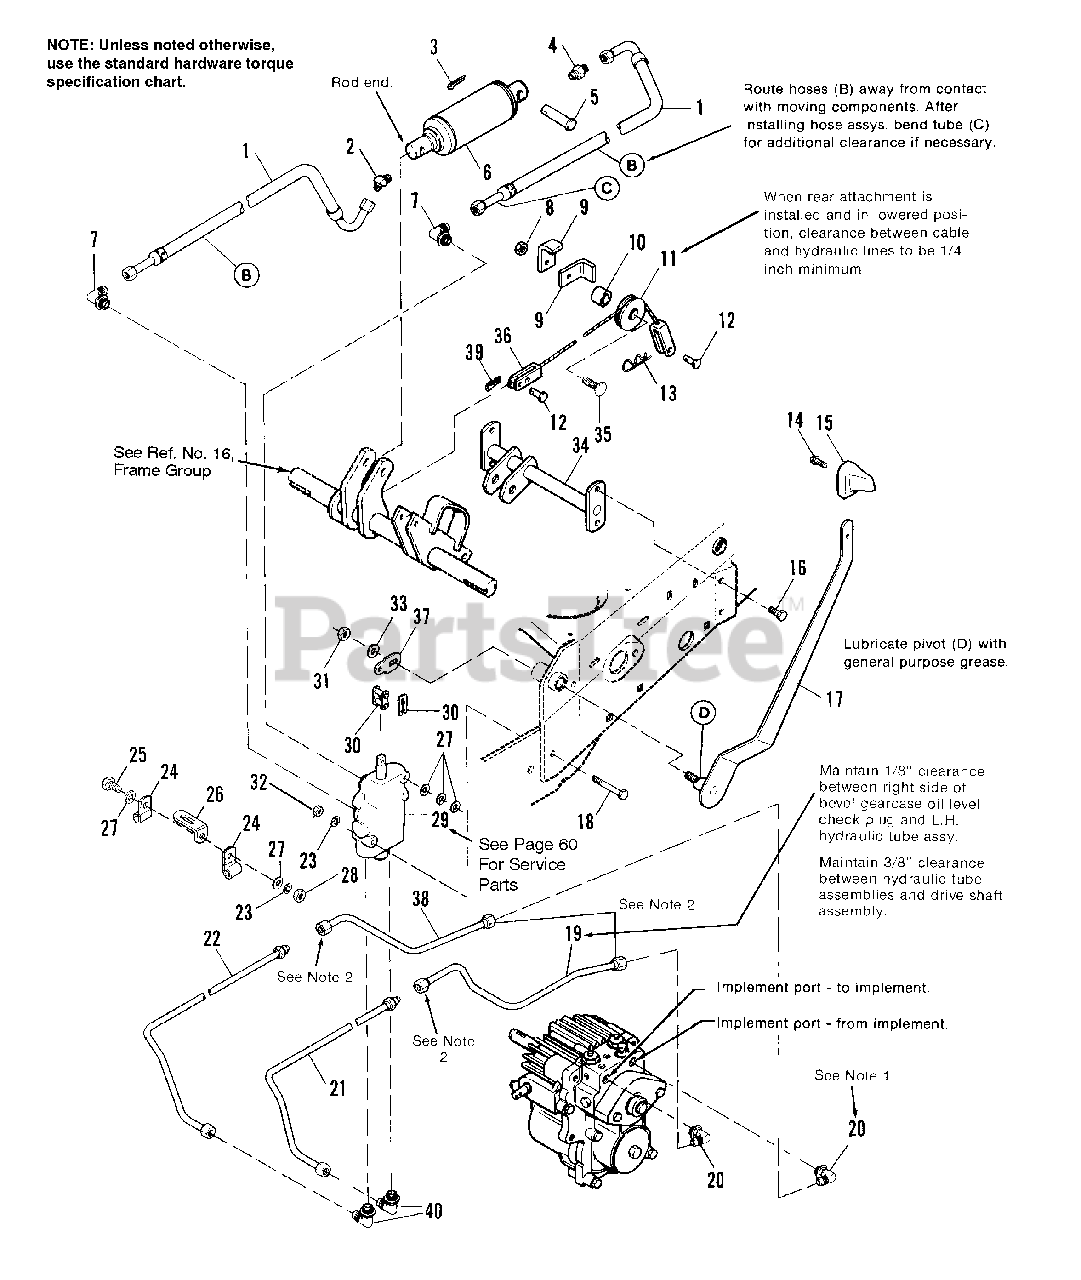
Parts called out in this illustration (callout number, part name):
1	HOSE, Hydraulic
2	FITTING, Elbow, 45°.
3	CLIP, Hairpin
4	CONNECTOR, 37° Male
6	CYLINDER
7	ELBOW, Adjustable, 37°.
8	LOCKNUT, Hex, Jam, 3/8-16
9	GUARD, Cable
13	CLIP, Spring
14	CAPSCREW, Hex Washer Hd, Plastite, 1/4-20 x 1
16	CAPSCREW, Hex. Washer Hd, Taptite 3/8-16 x 3/4
17	LEVER ASSEMBLY
18	CAPSCREW, Hex Hd, 1/4-20 x 2
19	TUBE ASSEMBLY (Manual Steer Models Only)
20	FITTING, Hydraulic
21	TUBE ASSEMBLY
22	TUBE ASSEMBLY
23	LOCKWASHER, 1/4
25	CAPSCREW, Hex Hd, 1/4-20 x 1-1/4
27	WASHER, Plain, 1/4
28	NUT, Hex, Full, 1/4-20
29	CONTROL VALVE ASSEMBLY
30	LINK, Connecting, #50
31	NUT, Hex Nylon Lock, 3/8-16
32	NUT, Hex Flange, Whiz Lock, 1/4-20
33	WASHER, Plain, 3/8
34	SUPPORT ASSEMBLY
35	CAPSCREW, Hex Hd, 3/8-16 x 1-1/4
36	CABLE ASSEMBLY
38	TUBE ASSEMBLY (Manual Steer Models Only)
39	PIN, Cotter, 3/32 x 3/4
40	FITTING, Hydraulic
